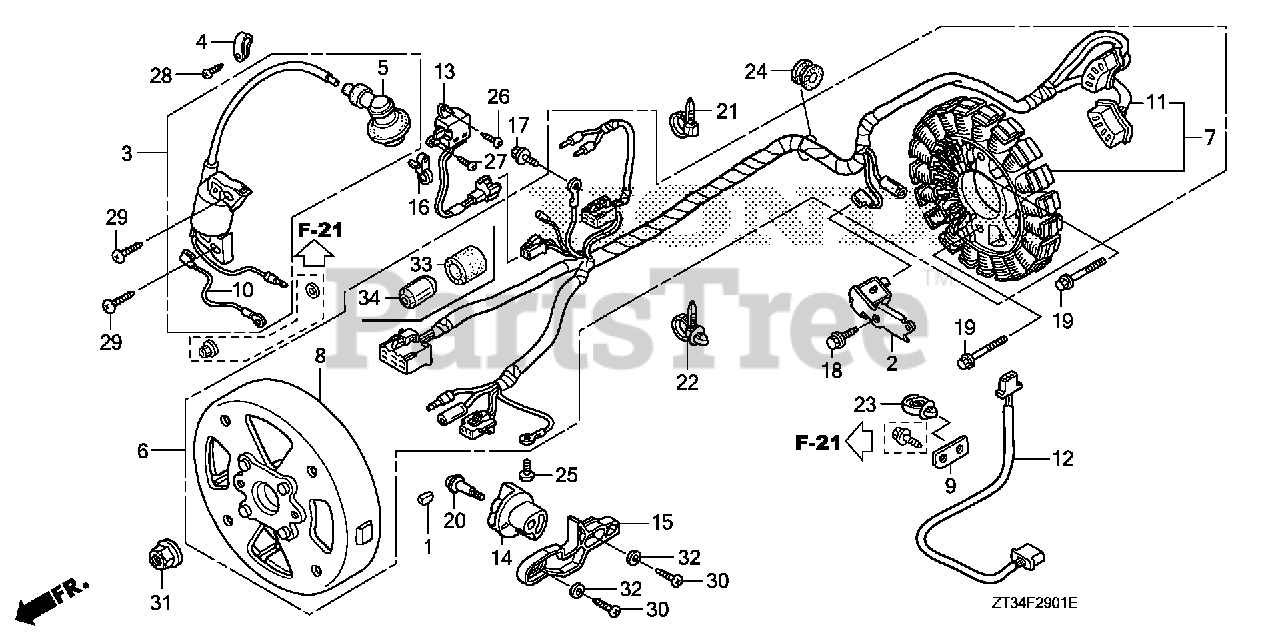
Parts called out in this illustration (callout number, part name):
1	KEY, SPECIAL
2	COIL, PULSER
3	COIL ASSY., IGNITION
4	CLAMP A, CABLE
5	CAP ASSY., NOISE SUPPRESSOR
6	GENERATOR ASSY.
7	STATOR ASSY.
9	BRACKET, WIRE HARNESS CLIP
10	WIRE, IGNITION GROUND
11	WIRE HARNESS ASSY., GENERATOR
12	SUB-WIRE ASSY.
13	SWITCH ASSY., ENGINE STOP
14	KNOB, ENGINE SWITCH
15	PLATE, ENGINE SWITCH
16	BAND, HARNESS
17	BOLT, FLANGE (5X8)
18	BOLT, FLANGE (5X12)
19	BOLT, FLANGE (5X25) (CT200)
20	SCREW, PAN (4X19)
21	BAND, WIRE (95MM)
22	STRAP, CABLE (118MM) (BLACK)
23	CLIP, WIRE HARNESS (25MM)
24	GROMMET, GENERATOR CORD
25	SCREW, PAN (5X8)
26	SCREW, TAPPING (3X10)
27	SCREW, TAPPING (3X16)
28	SCREW, TAPPING (5X12)
29	SCREW, TAPPING (6X20)
30	SCREW, TAPPING (5X20) (PO)
31	NUT, FLANGE (10MM)
32	WASHER, PLAIN (5MM)
